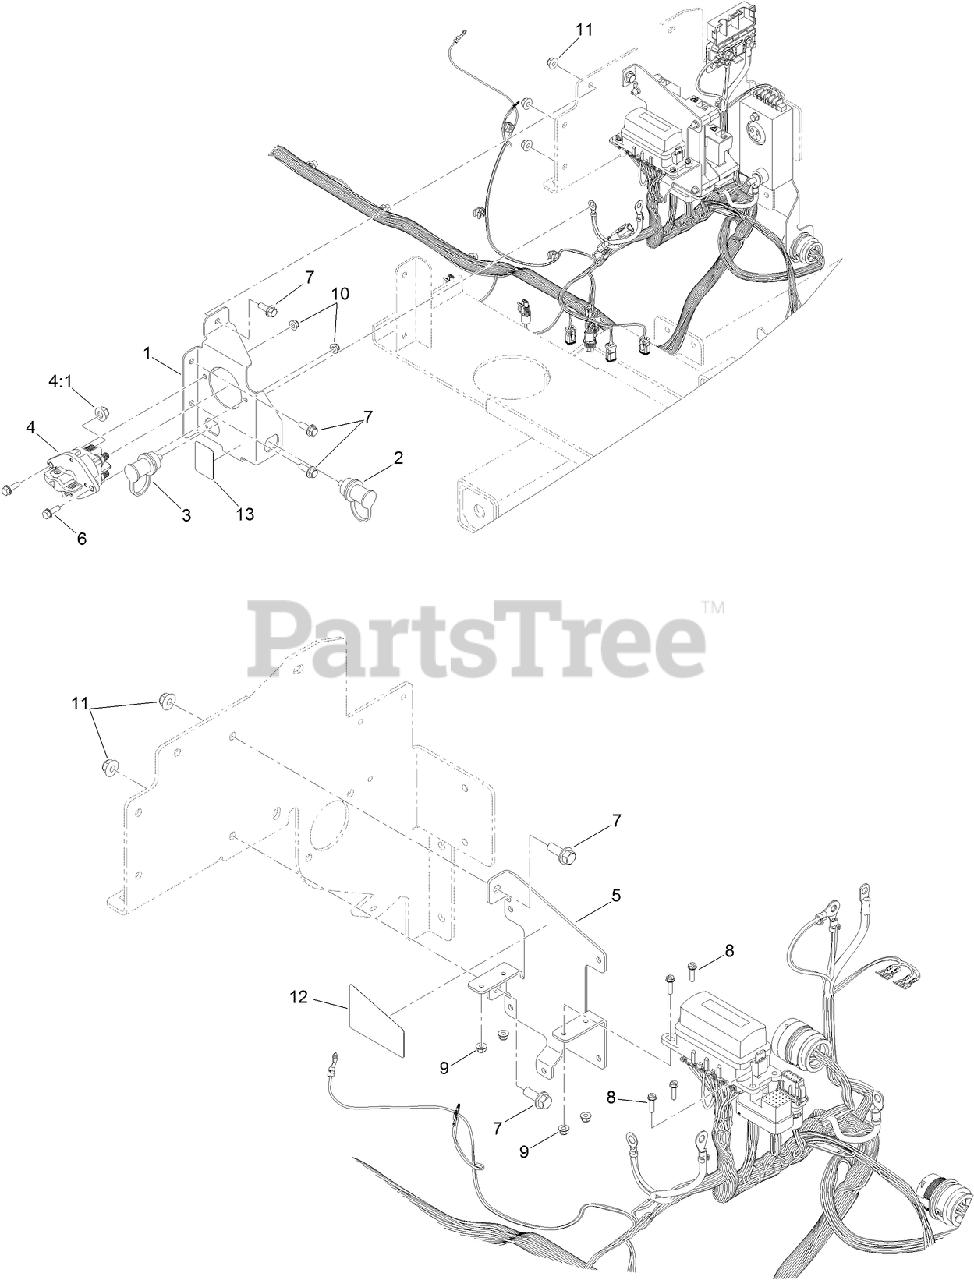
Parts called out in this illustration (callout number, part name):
1	BRACKET-ELECTRICAL
2	STUD-JUMPER, POSITIVE
3	STUD-JUMPER, NEGATIVE
4	SWITCH-DISCONNECT
4:1	NUT-HF
5	BRACKET-ELECTRICAL
6	SCREW-HHF
7	SCREW-HHF
8	SCREW-HWH
9	NUT-HF
10	NUT-HF, NI
11	NUT-HF, NI
12	DECAL-FUSES
13	DECAL-BATTERY POWER
